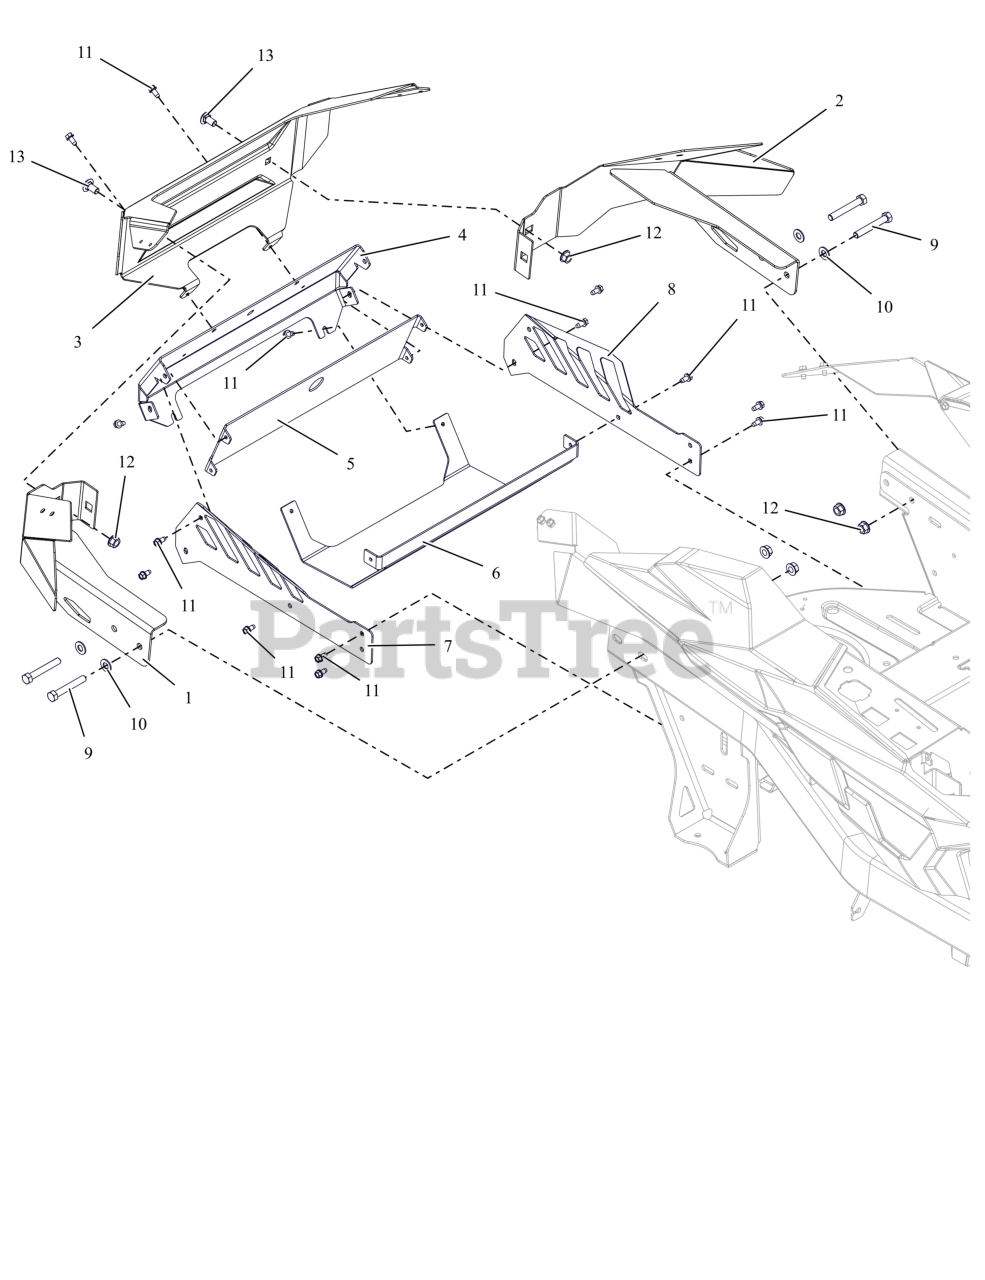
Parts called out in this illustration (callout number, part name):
1	WLDMT, BUMPER - RH (BLACK)
2	WLDMT, BUMPER -LH (BLACK)
3	PLATE- GRAVELY BACK WRAP
4	SHIELD- MUFFLER
5	SHIELD, HEAT (BLACK)
6	MUFFLER- SHEILD- GRASS BROWN
7	KIT, RH MUFFLER GUARD W/ DECALS
8	KIT, LH MUFFLER GUARD W/ DECALS
9	BLT, HEX .38-16X2.50 G5 ZCC
10	WSHR,FLT .406X.812X.065 ZCC
11	SCR-TAP .25X.50 HWH ZB500
12	NUT-LK-CTR-FLG .375-16 GF ZCC
13	BTL,RHSSN .375-16 X 0.75 G5 FPB
